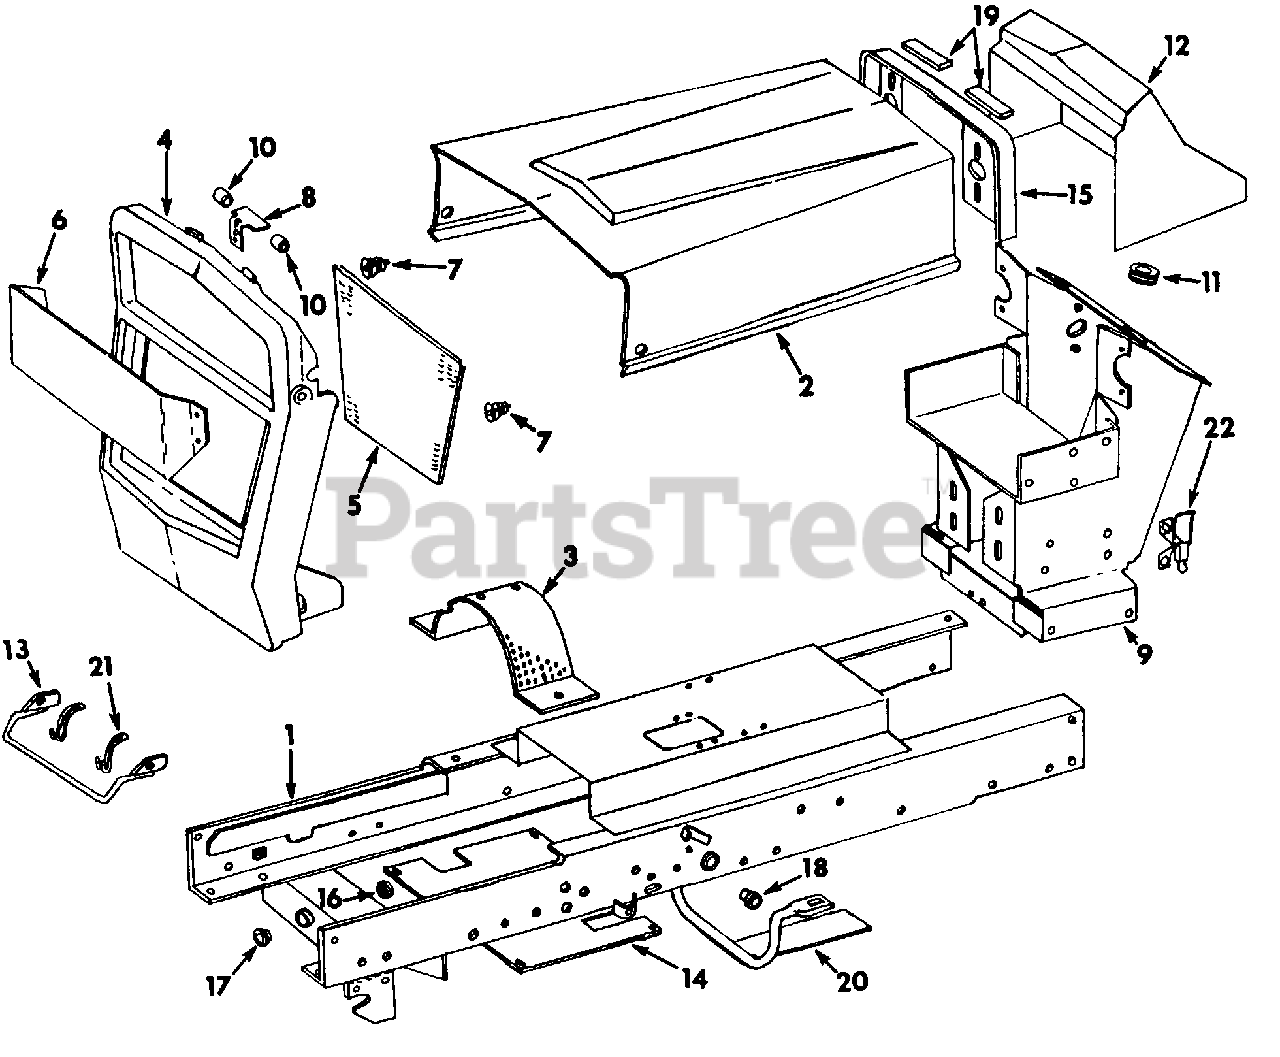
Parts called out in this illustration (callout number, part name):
1	Frame Assy
3	Shield, Clutch
4	Housing, Grille
6	Strip, Panel
7	Spring, Hold Down
8	Bracket Assy, Front Hood
9	Pedestal Assy
10	Pad, Hood Bumper
11	Grommet, Instrument Panel
12	Cowl, Instrument Panel
13	Hitch Assy, Quick
14	Sheet, Bottom Clutch Shield
15	Support, Rear Hood
16	Washer, Front Axle Pivot Pin Rear
17	Bracket, Front Axle Pivot Pin Front
18	Bearing, Clutch Pedal Shaft
19	Pad, Hood Bumper
20	Guard Assy, Suction Tube
21	Spring, Latch
22	Latch Assy, Hood
